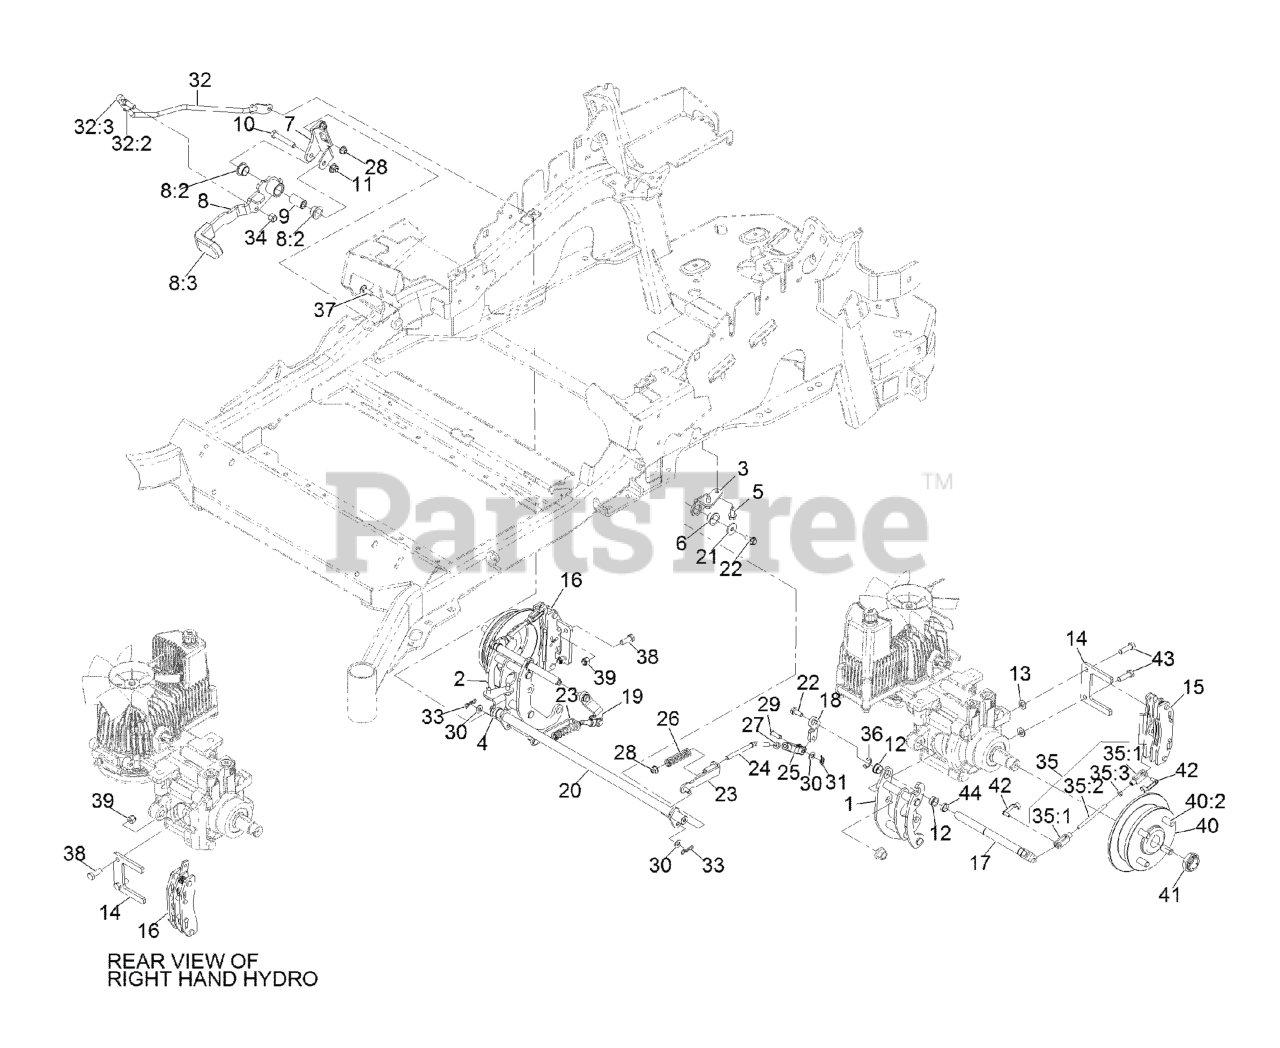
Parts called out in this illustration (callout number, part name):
1	MOUNT-BELLCRANK, LH
2	MOUNT-BELLCRANK, RH
3	MOUNT-PIVOT, LH
4	MOUNT-PIVOT, RH
5	Screw-HWH 5/16-18 X 3/4 Tf
6	BUSHING-FLANGE
7	BRACKET-MOUNT
8	BRAKE LEVER ASM W/ GRIP
8:2	BUSHING-FLANGE
8:3	GRIP-LEVER
9	HANDLE-PIVOT, BRAKE
10	SCREW-HH
11	NUT-HF, NI
12	BUSHING
13	WASHER-FLAT
14	PLATE-MOUNT, BRAKE
15	CALIPER-BRAKE
16	CALIPER-BRAKE, RH
17	BELLCRANK
18	ARM-INNER, LH
19	ARM-INNER, RH
20	SHAFT-CROSS
21	WASHER-FLAT
22	SCREW-HHF
23	BRACKET-L
24	LINKAGE-MID
25	YOKE-OFFSET
26	SPRING-COMPRESSION
27	NUT-JAM
28	NUT-HF, NI
29	PIN-CLEVIS
30	WASHER-PLAIN
31	PIN-COTTER, LOCKING
32	FRONT LINKAGE ASM
32:2	END-TIE ROD, RH
32:3	NUT-HJ
33	PIN-COTTER, LOCKING
34	NUT-LOCK
35	REAR LINKAGE ASM
35:3	NUT-JAM
37	BOLT-CARR
38	SCREW-HH
39	NUT-LOCK, NI
40	WHEEL HUB ASM
40:2	STUD-WHEEL
41	LOCKNUT
42	PIN-CLEVIS, SPRING
43	SCREW-LOCK, PATCH
